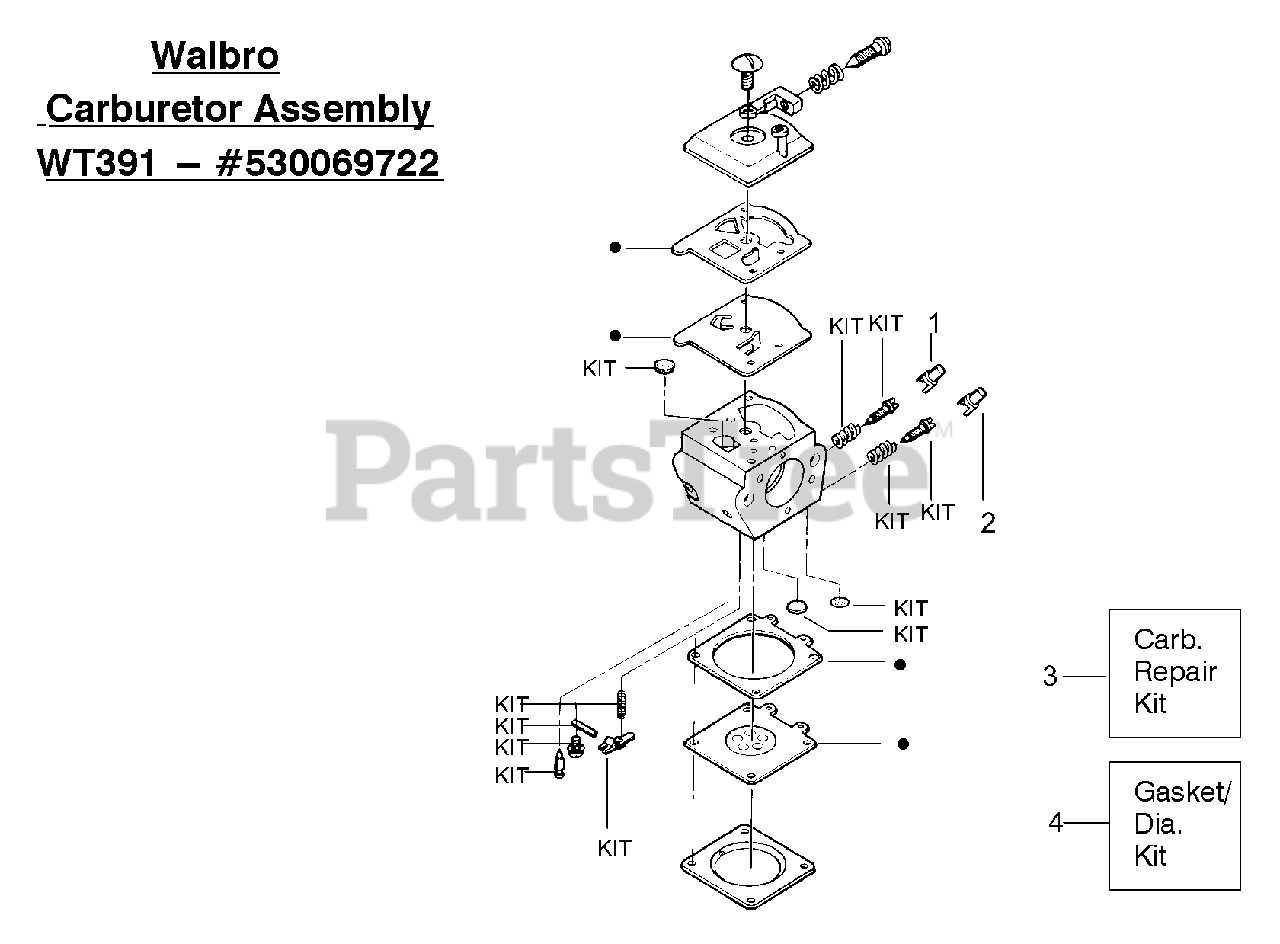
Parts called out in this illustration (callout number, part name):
1	Limiter Cap-High
2	Limiter Cap-Low
3	Carburetor Repair Kit
4	Gasket Diaphragm Kit
530069722	Carburetor Assembly - WT391
